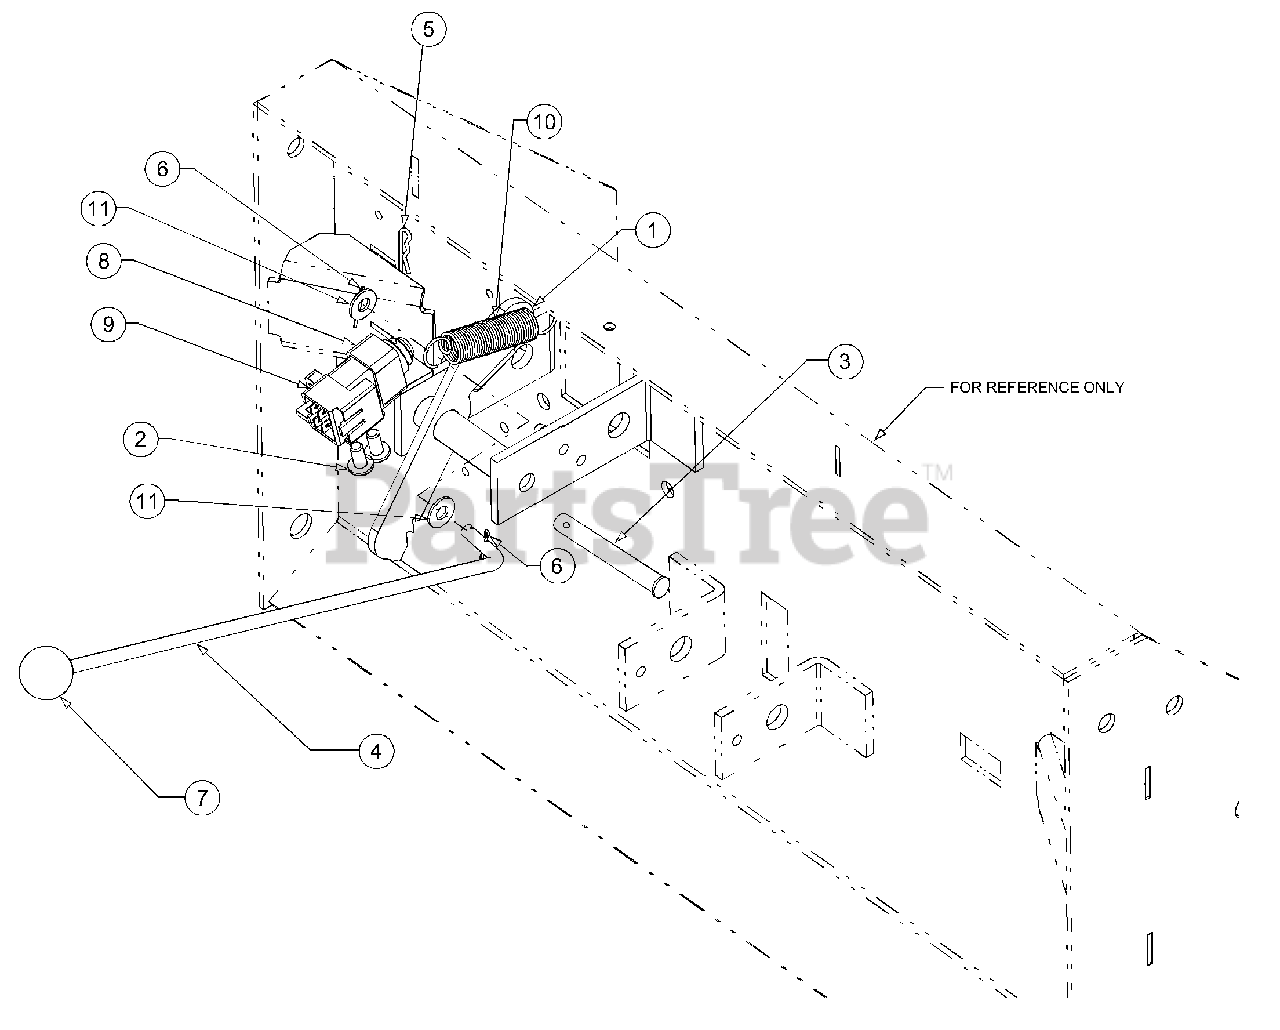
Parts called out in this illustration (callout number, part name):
1	Lever Assembly, Parking Brake
2	Screw, Hi-Lo, 1/4-20 x .5
3	Pin, Clevis
4	Rod, Brake Lock
5	Pin, Cotter
6	Pin, Cotter 1/16 x .75
7	Knob, Ball
8	Cover, Protective
9	Snap Mount Switch, Interlock
10	Spring, Extension, .637 x 2.972
11	Washer, Flat .25 x .630 x .0515
